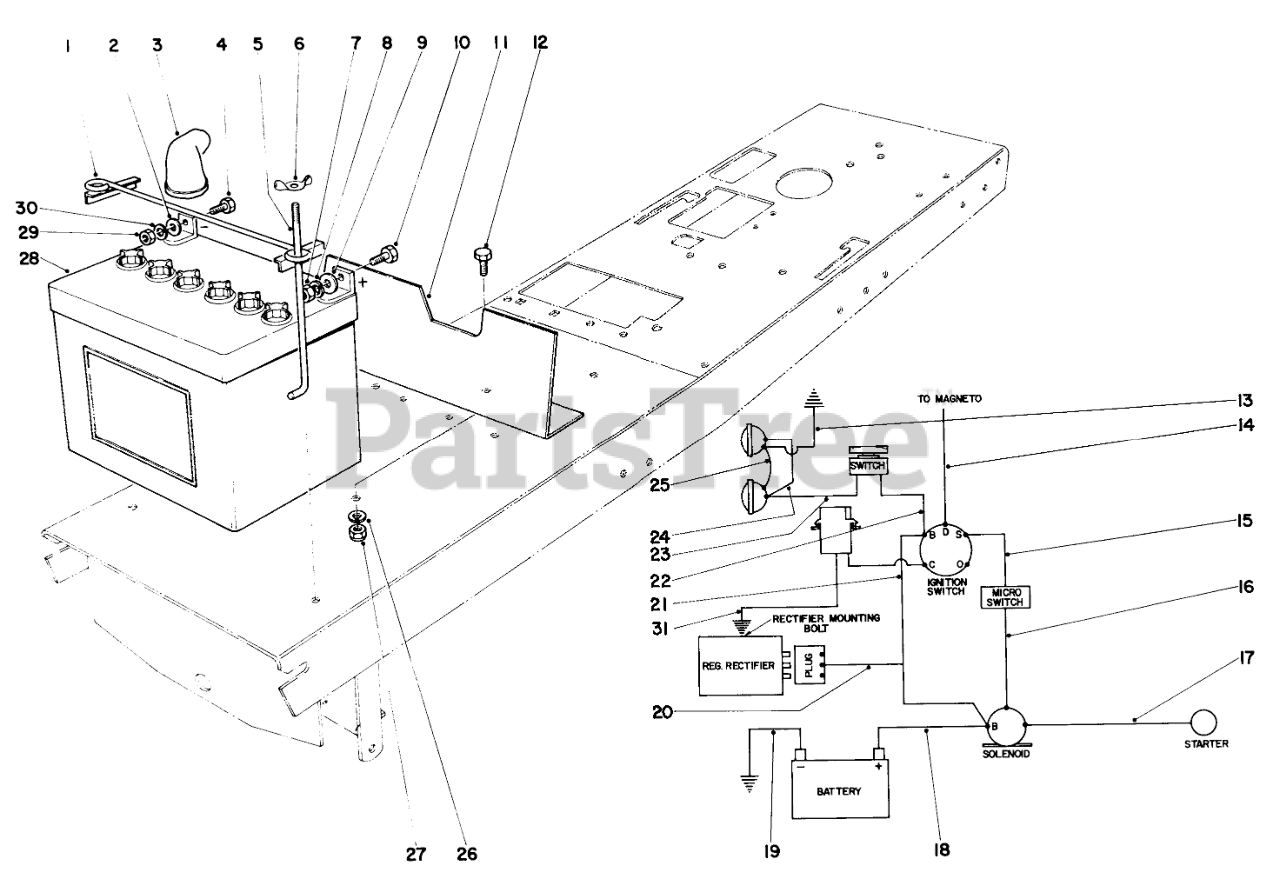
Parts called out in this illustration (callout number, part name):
1	Battery Clamp
2	Washer
3	Battery Boot
4	SCREW-HH
5	BATTERY BOLT
6	NUT-WING
7	NUT-HEX
8	WASHER-LOCK
9	Washer
10	SCREW-HH
11	Heat Shield
12	SCREW-HH
13	Wire Assy.-Red
14	Wire Assy. Switch To Magneto
15	Wire Assy. Switch to Micro Switch
16	Wire Assy. Micro Switch to Solenoid
17	Wire Assy. Solenoid to Starter
18	Wire Assy. Solenoid to Battery
19	Wire Assembly
20	Wire Assy. Switch to Reg. Rectifier
21	Wire Assy. Switch to Solenoid
22	Wire Assy.-Red
23	Wire Assy.
24	Wire 960
25	Wire 960
26	WASHER-LOCK
27	Nut
28	Battery
29	NUT-HEX
30	WASHER-LOCK
31	Wire Assy.
